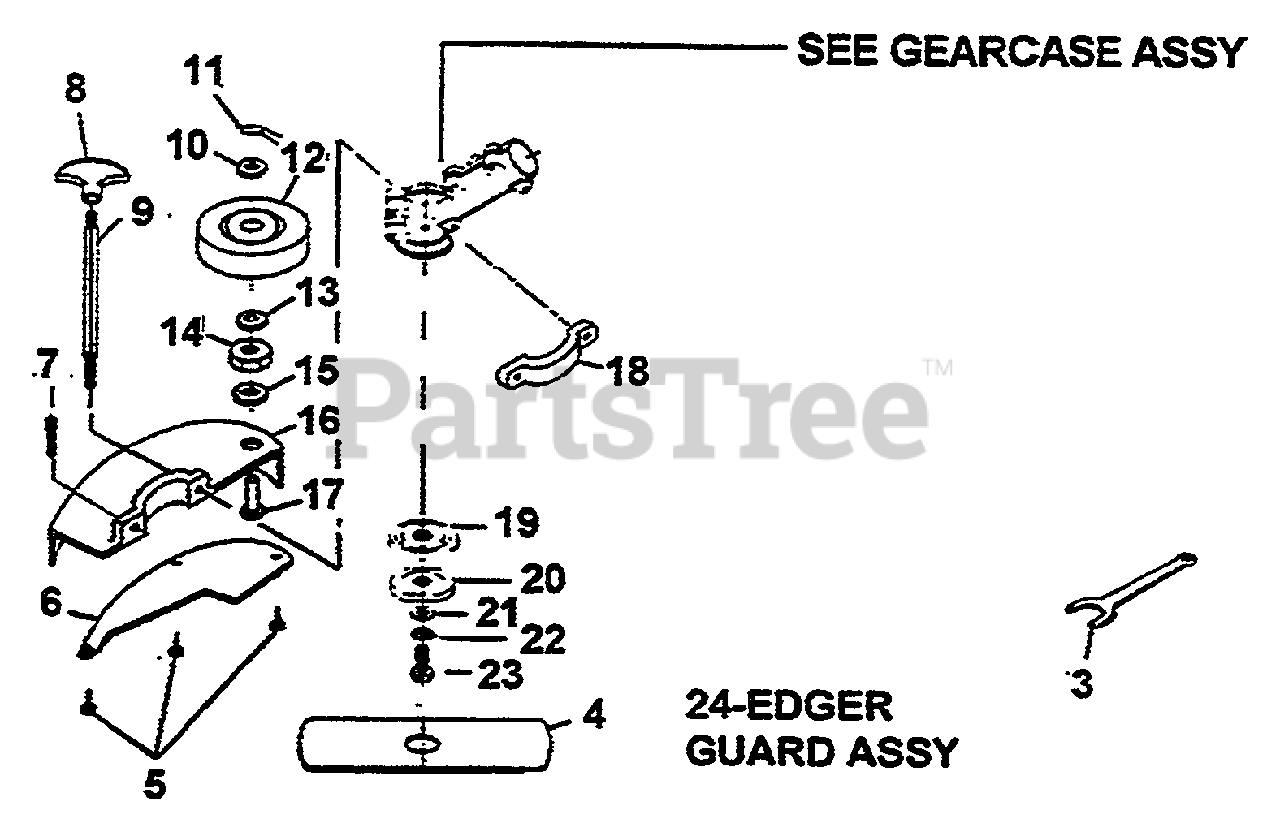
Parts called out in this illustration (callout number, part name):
3	SPANNER WRENCH
4	EDGER BLADE
5	SCREW
6	EDGER SHIELD
8	KNOB
9	SHAFT & KNOB KIT
11	COTTER PIN
14	NUT
16	EDGER GUARD
17	EDGER AXLE
20	HOLDER B
22	WASHER
23	BOLT
24	EDGER GUARD ASSY
